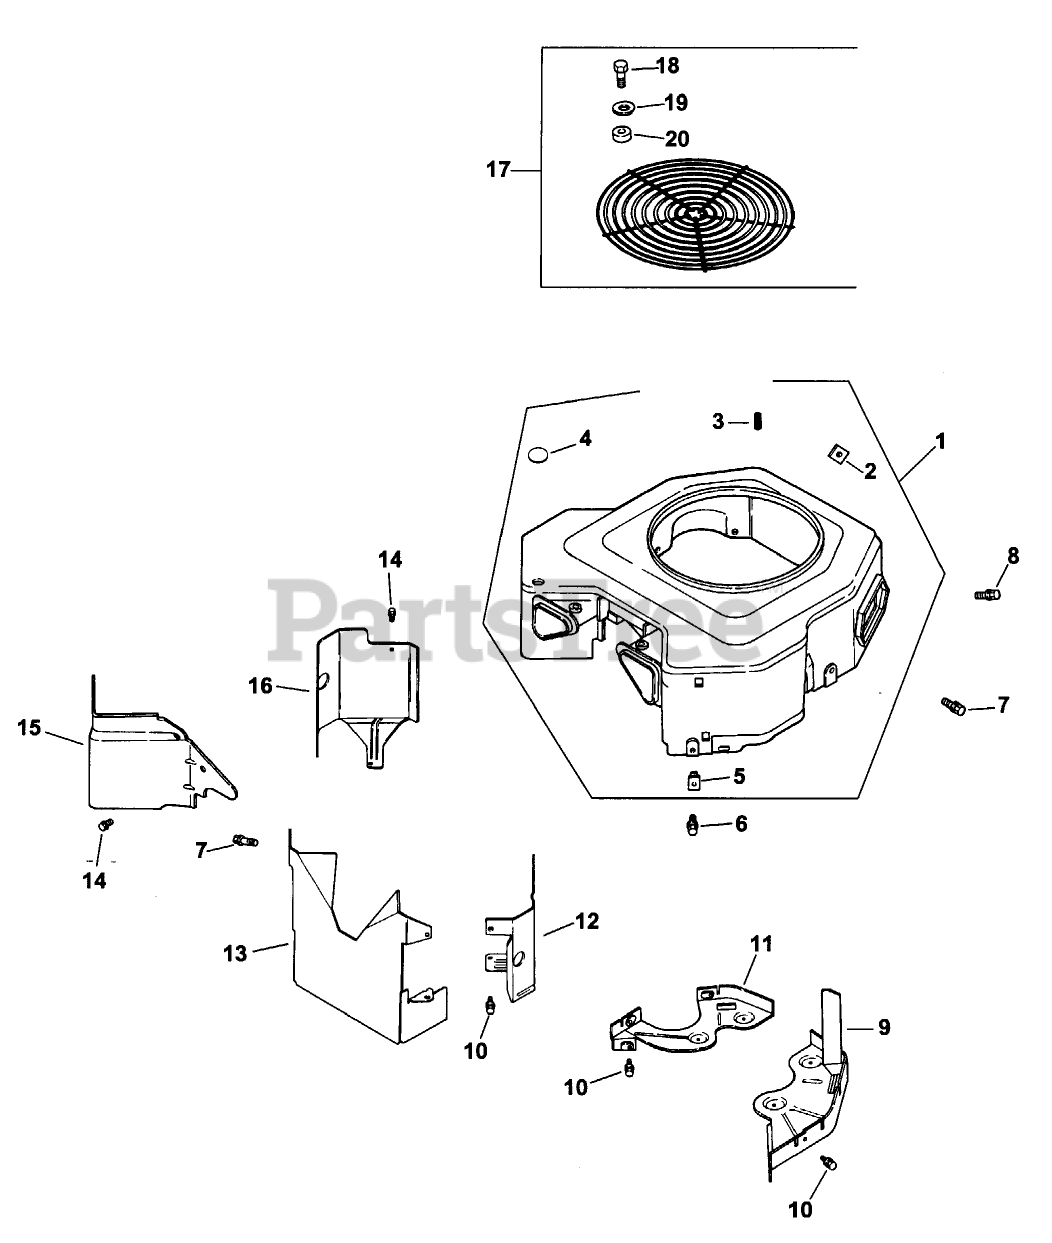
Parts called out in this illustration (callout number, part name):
1	Housing, blower (Includes 2-5)
2	Nut
3	Screw-Set
4	Plug-Button
5	Nut-Plastic
6	Screw-HF
7	Screw-HF
8	Screw
9	Plate-Backing #2 Side
10	Screw
11	Plate-Backing #1
12	Baffle-Cylinder, #2
13	Baffle-Valley #1 Side
14	Screw
15	Baffle-Valley #2 Side
16	Baffle-Cyl. #1 Side
17	Kit, guard (Includes 18-20,Threaded insert Qty. 3] 24 332 01)
18	Screw
19	Washer
20	Spacer
